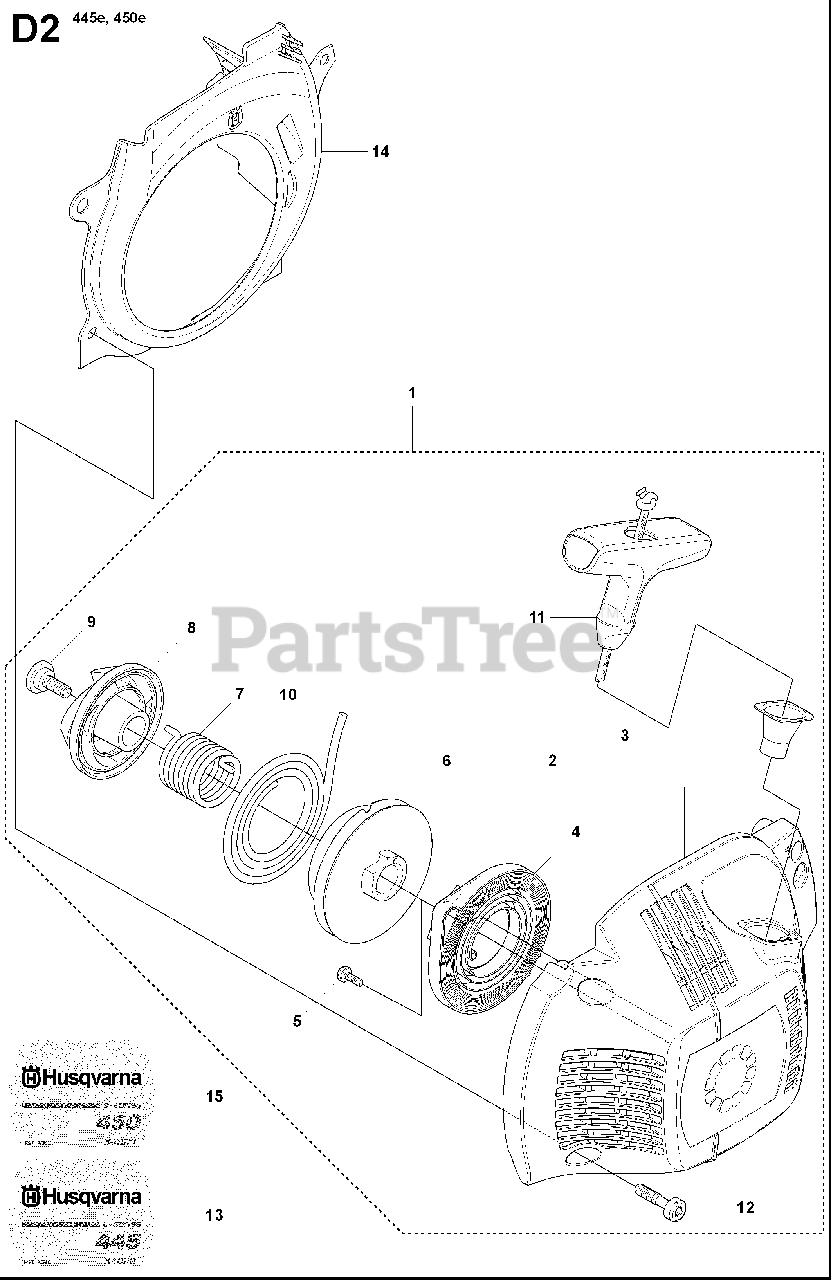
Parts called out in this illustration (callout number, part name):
1	STARTER ASSY
2	STARTER HOUSING
4	RETURN SPRING
6	STARTER PULLEY
10	STARTER ROPE
14	COOLING AIR CONDUCTOR
